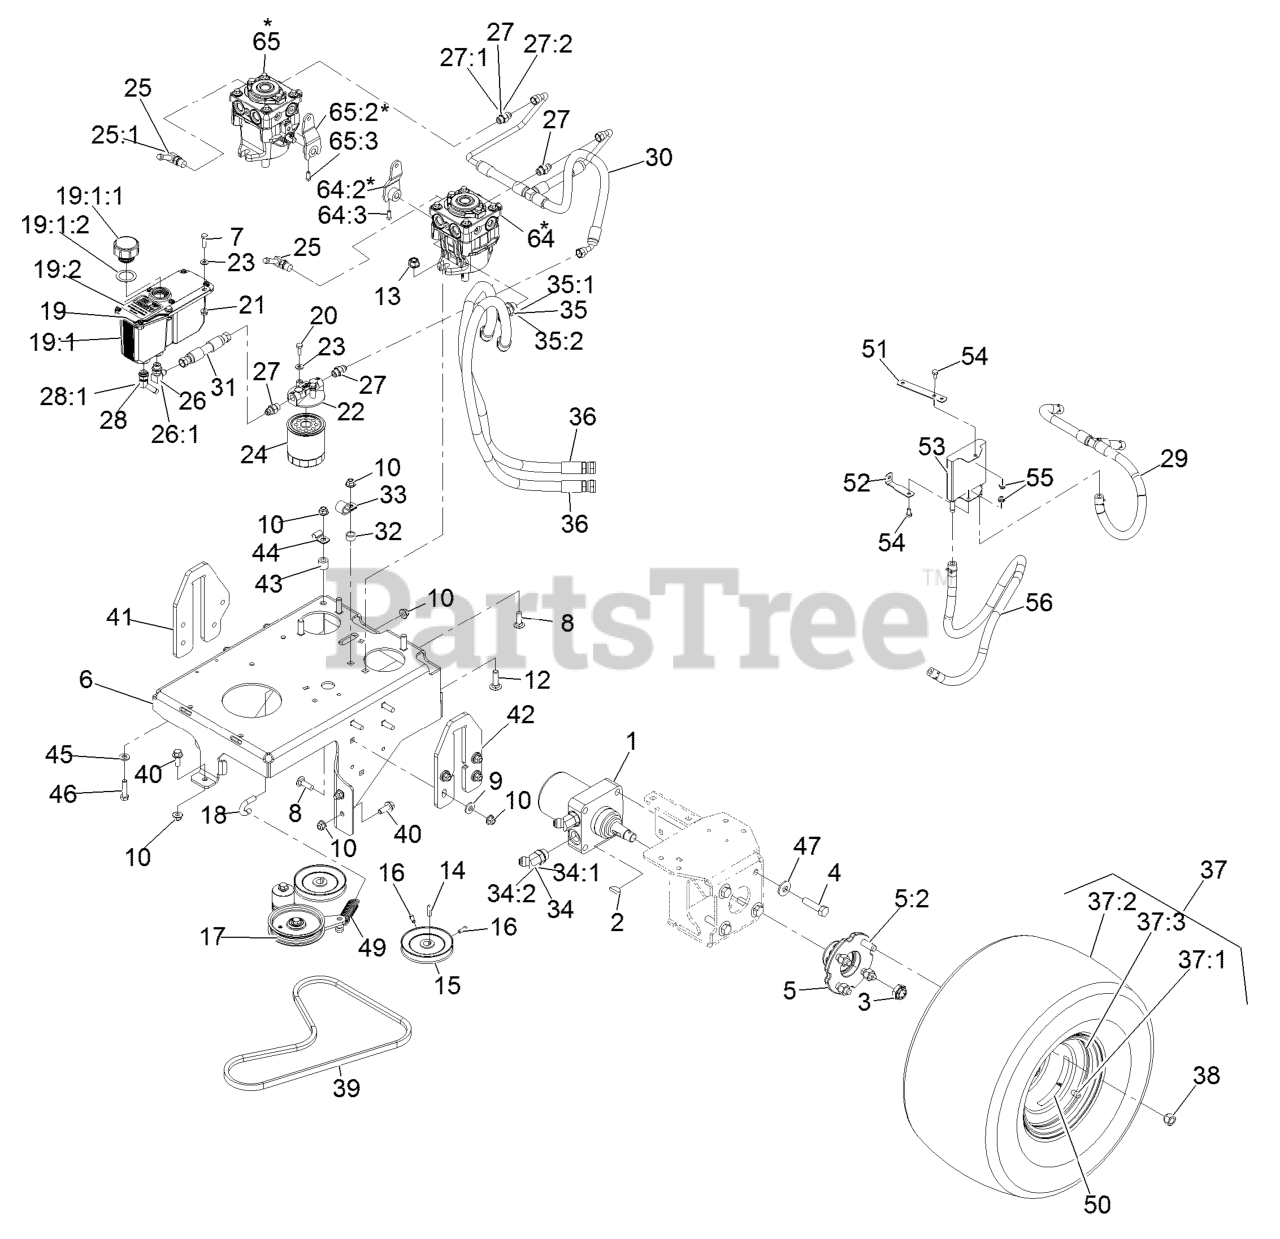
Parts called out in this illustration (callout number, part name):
1	MOTOR, WHEEL TE230
2	KEY-WOODRUFF
3	NUT-LOCK
4	SCREW-HH
5	WHEEL HUB ASM
5:2	STUD-TYPE, DRIVE
6	WELDMENT, FRAME
7	SCREW-HH
8	BOLT-CARR
9	WASHER-BELLEVILLE
10	NUT-HF, NI
12	SCREW-HH
13	NUT-HF, NI
15	PULLEY-PUMP
16	SCREW-SET
17	PUMP IDLER ASM
18	ANCHOR, SPRING
19	RESERVOIR ASM
19:1	Reservoir-Hyd
19:1:1	Cap-Reservoir, HYD
19:1:2	GASKET-CAP
19:2	DECAL-HYDRAULIC TANK
20	SCREW-HH
21	NUT-HHF
22	HEAD-FILTER
23	WASHER-FLAT
24	FILTER-25 MICRON, BI-DIRE
25	FITTING-ELBOW, 90
25:1	O-RING
26	FITTING-ELBOW, 90 DEG
27	FITTING-STRAIGHT
28	FITTING-BARBED, 45 DEG
28:1	O-RING
29	HOSE ASM-CASE DRAIN
30	HOSE ASSEMBLY - CHARGE
31	HYD HOSE ASM
32	SPACER-WHEEL
33	CLIP-LOOM
34	FITTING-HYD, 45 DEG
35	FITTING-HYD, 45 DEG
36	HYD HOSE ASM
37	WHEEL/TIRE ASM
37:1	RIM-8 INCH
37:3	Stem-Valve
38	NUT-LUG
39	BELT-V, LOWER PTO
40	SCREW-HHF 3/8-16 X 1
41	PLATE-LIFT, RH
42	PLATE, LIFT LH
44	CLIP-TUBE
45	WASHER-FLAT
46	SCREW-HH
47	WASHER-SPRING
49	SPRING-EXTENSION
51	BRKT-COOLER MOUNT, TOP
52	BRKT-COOLER MOUNT, BOTTOM
53	COOLER-OIL
54	SCREW-HH
56	HOSE ASM
64	PUMP W/ARM - LEFT
64:2	ARM-HYDRO
64:3	SCREW-SET
65	PUMP W/ARM -RIGHT
65:2	ARM-HYDRO
65:3	SCREW-SET
